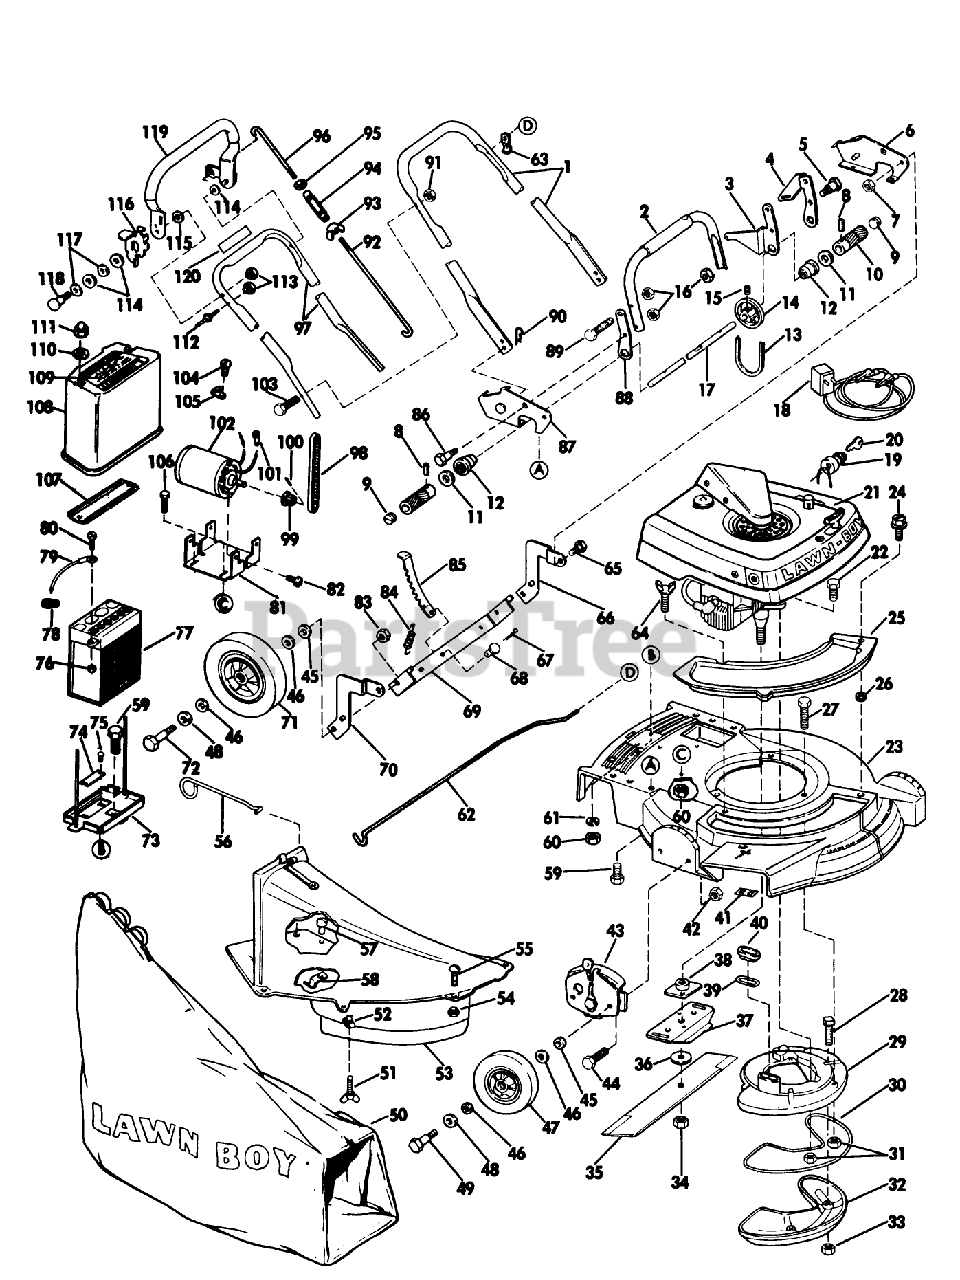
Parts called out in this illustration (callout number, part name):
9	GREASE PLUG
10	LEFT ROLLER
24	SCREW SEMS TRM HEX HD
33	LOCKNUT E
34	NUT-BLADE
38	PLATE AND COLLAR ASM
39	GASKET S
45	WASHER WROUGHT
49	BOLT WHEEL
50	89802 LB WHOLE GOODS
52	SPEED NUT ARDEN
53	Skirt Assembly
62	ROD & CLIP
65	BOLT-SHOULDER
78	RETAINER ARDEN
83	LOCKNUT
84	SPRING N.A.S
86	BOLT PIONEER
90	HAIR PIN
104	SCREW S
106	SCREW S
111	PALNUT S
114	WASHER M
118	BOLT PIONEER
